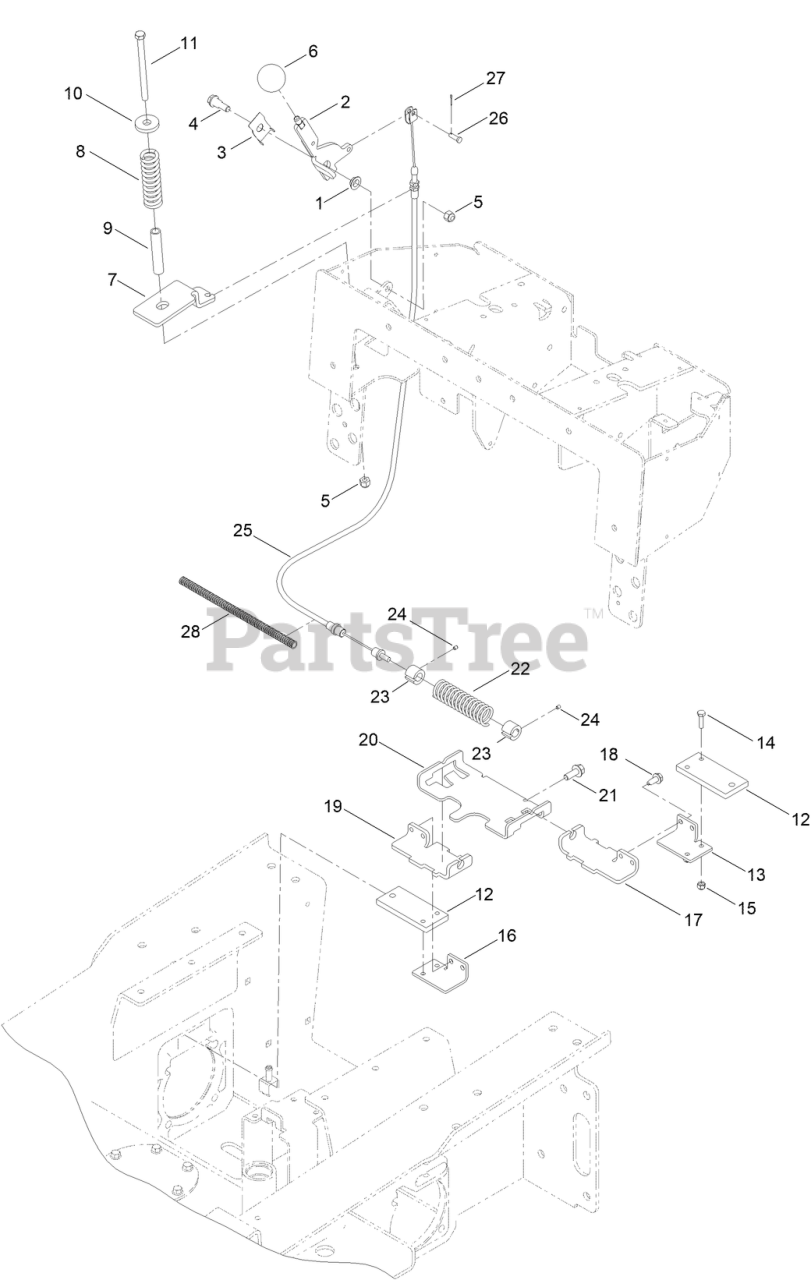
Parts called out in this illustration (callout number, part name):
1	BUSHING-FLANGE
2	HANDLE-BRAKE
3	SPRING-LEAF
4	BOLT-SHOULDER
5	NUT-LOCK, NI
7	BRACKET-CABLE, SPRING
8	SPRING-COMPRESSION
9	SPACER-SPRING
10	WASHER-HARDENED
11	SCREW-HH
12	PLATE-BRAKE
13	BAR-LINK, BRAKE L.H.
14	SCREW-HH
15	NUT-LOCK, NI
16	BAR-LINK, BRAKE R.H.
17	BRACKET-MOUNTING, BRAKE L.H.
18	SCREW-HWH
19	BRACKET-MOUNTING, BRAKE R.H.
20	SUPPORT-BAR, BRAKE
21	SCREW-HHF
23	TUBE-GUIDE
24	SCREW-HSH
25	CABLE-BRAKE
26	PIN-CLEVIS
27	PIN-COTTER
28	TUBE-CONVOLUTED
